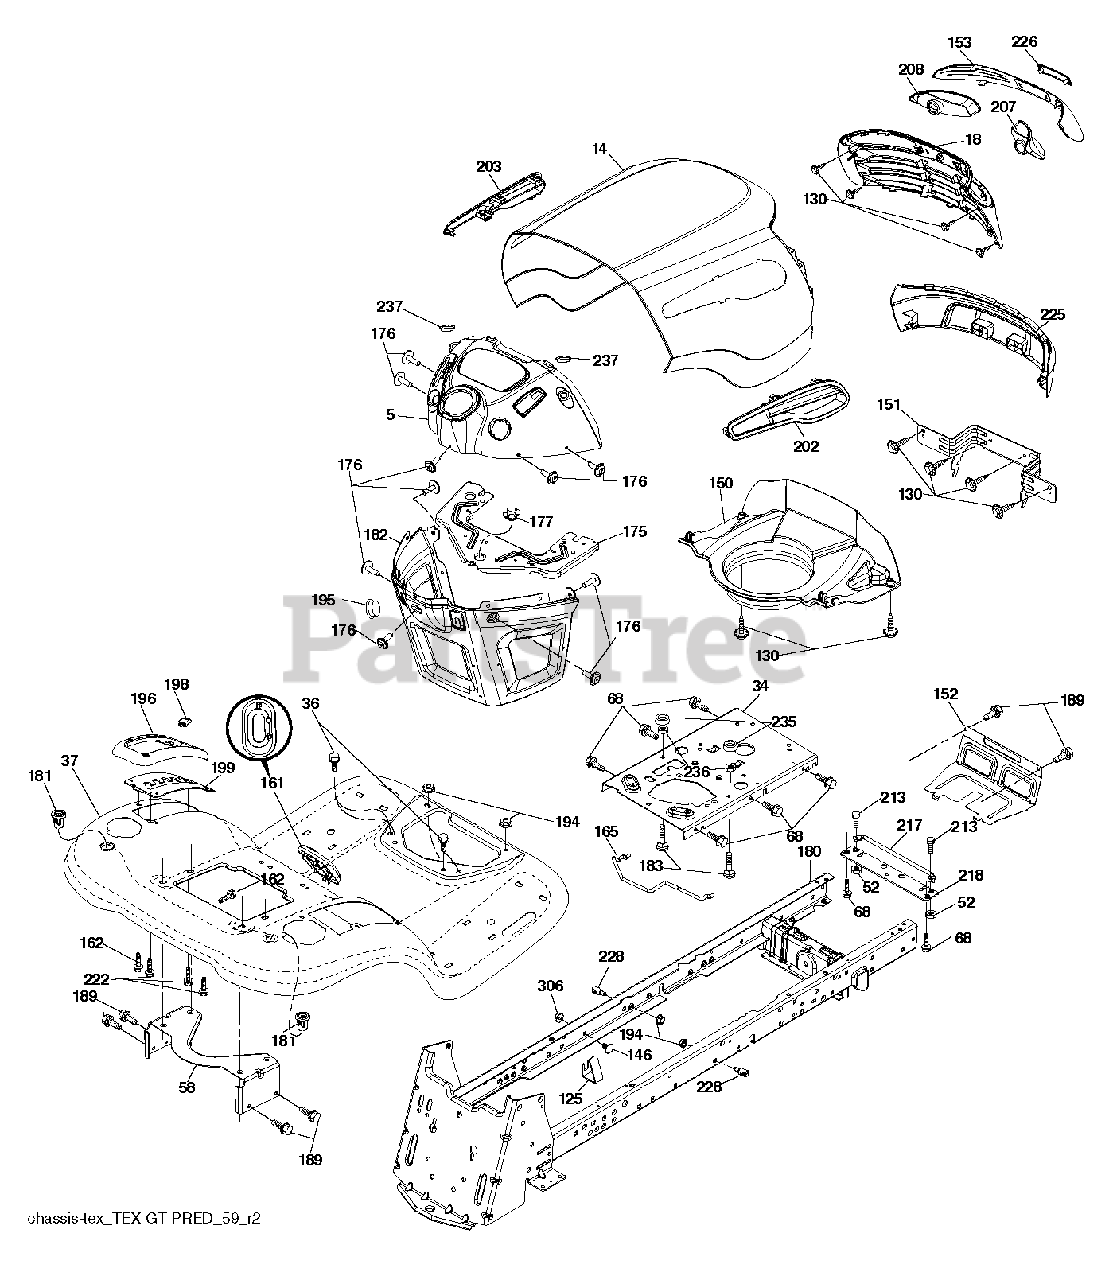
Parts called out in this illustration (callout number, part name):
14	HOOD.PNT.PREDATOR.YT/GT.BLACK
18	GRILLE.SVC.PREDATOR.YT.TEX
34	PLATE.ENGINE.WELDED.CHASSIS
36	SCREW 5/16"
52	LOCKNUT
58	BRKT.SUPPORT.FNDR/TANK
68	SCREW LT
125	CLIP.FUEL.LINE
130	SCREW.#10 X 0.750.BOS (2 2)
146	BOLT.RDHD.SHT.SQNK.3/8-16X5/8
150	PREDATOR.YT.GT.HOOD.AIR DUCT
151	BRACKET.PIVOT.PREDATOR
152	SHIELD.BROWNING.W/TEX
153	LENS.BAR.PREDATOR.YT.CLEAR
161	CONSOLE.FUEL.WINDOW.STGT.BLACK
162	SCREW.HI-LO.CONSOLE
165	SUPPORT.TANK.REAR.W/TEX
175	PLATE.CROSSMEMBER.HUSQ
176	SCREW.#10-24X5/8.RN.QU
177	BUSHING,STEERING
180	CHASSIS.GT.SLOPED.DRAWBAR.
181	FEND/FTRST.PCH.CPH.NFW
182	DASH LOWER.HUSQ.PRED NO CRUISE
183	BOLT.5/16-18X1-1/4 FULL THD
189	SCREW
194	NUT LOCK HEX FLANGE 5/16-18
195	PLUG.HOLE.DASH.
199	PLATE DECK LIFT
202	VENT.SIDE.HOOD.RH.PREDATOR.BLK
203	VENT.SIDE.HOOD.LH.PREDATOR.BLK
213	BOLT
217	ROD.PIVOT.HOOD
218	X-PIECE.HOOD.STOP.NON/
222	SCREW.1/4-20X5/8
228	STUD.FASTNER.W/ANTI-ROTATE
235	SPACER FENDER
236	NUT.CENTERLOCK.5/16-
237	PLUG.MOUNT.CARGO.BLK
306	NUT LOCK FLG 3/8-16 UNC
